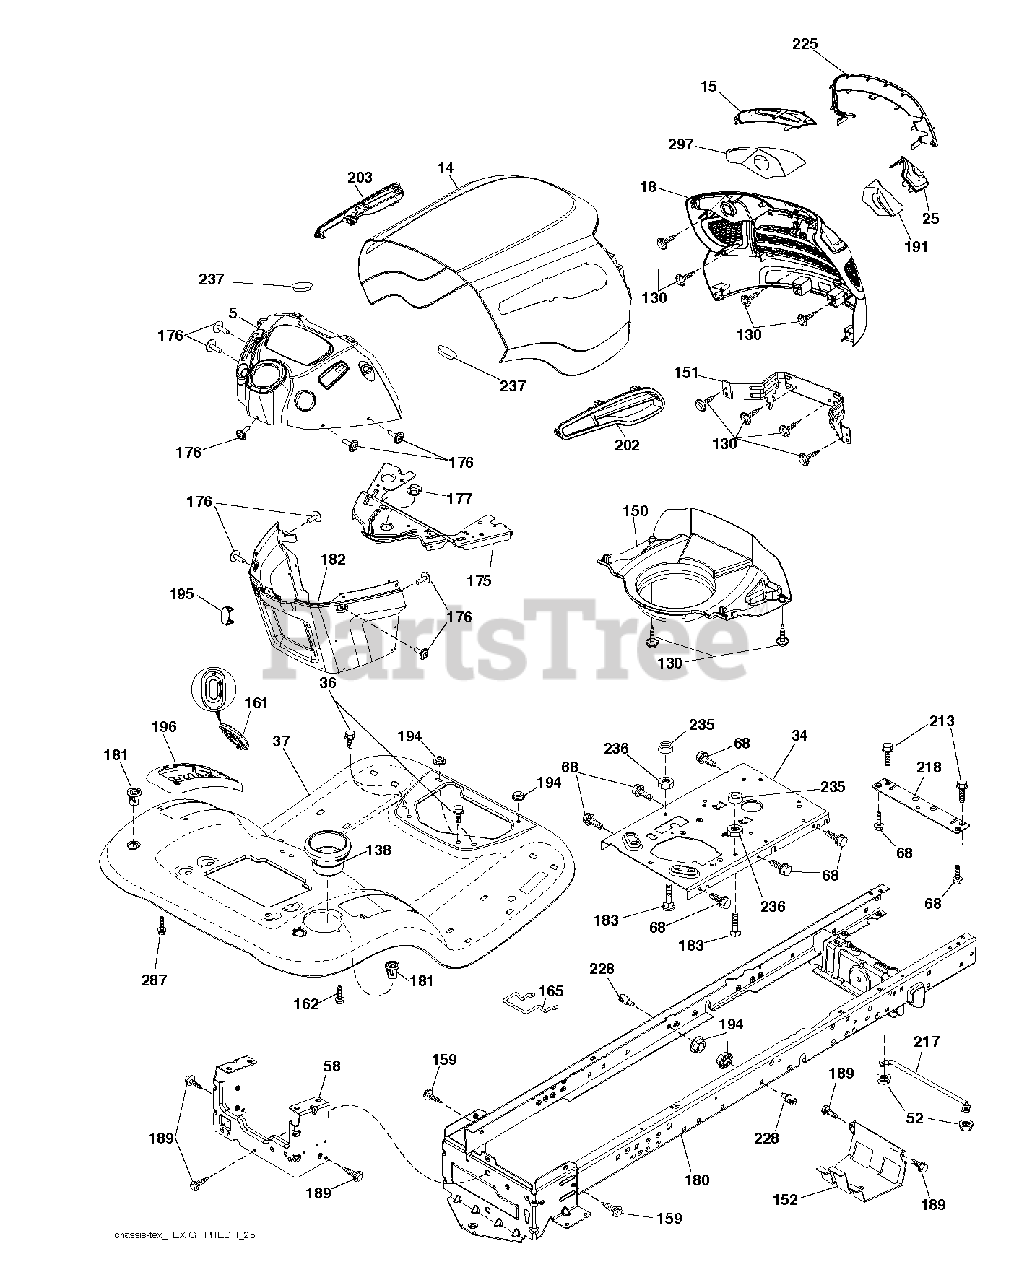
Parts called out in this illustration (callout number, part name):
5	DASH.UPPER.PREDATOR.M/C.BLACK
14	HOOD.PNT.PREDATOR.YT/GT.BLACK
15	LENS.MCCULLOCH.GT.LH
18	GRILLE.PREDGT2.GEN
25	Lens, RH Mcculloch GT
34	PLATE.ENGINE.WELDED.CHASSIS
36	SCREW 5/16"
37	FENDER.TLT.PCH.CPH.FW.ROS.428
52	LOCKNUT
58	DRAWBAR UPPER 2PC SMALL FENDER
68	SCREW LT
130	SCREW.#10 X 0.750.BOS (2 2)
138	CUPHOLDER.TL.TEX.BLACK
150	PREDATOR.YT.GT.HOOD.AIR DUCT
151	BRACKET.PIVOT.PREDATOR
152	SHIELD.BROWNING.W/TEX
159	SCREW, 3/8-16X3/4
161	WINDOW.FUEL.LT.TEX.BLACK
162	SCREW.HI-LO.CONSOLE
165	SUPPORT.TANK.REAR.W/TEX
175	PLATE.CROSSMEMBER.HUSQ
176	SCREW.#10-24X5/8.RN.QU
177	BUSHING STEERING
180	CHASS.WLDMNT.TL.12GA/2P.48/54
181	FEND/FTRST.PCH.CPH.NFW
182	DASH LOWER.HUSQ.PRED NO CRUISE
183	BOLT.5/16-18X1-1/4 FULL THD
189	SCREW
191	REFLECTOR.MCCULLOCH.GT.RH
194	NUT LOCK HEX FLANGE 5/16-18
195	PLUG.HOLE.DASH.
202	VENT.SIDE.HOOD.LH.PREDATOR.BLK
203	VENT.SIDE.HOOD.RH.PREDATOR.BLK
213	BOLT
217	ROD.PIVOT.HOOD
218	X-PIECE.HOOD.STOP.NON/
228	STUD.FASTNER.W/ANTI-ROTATE
235	SPACER FENDER
236	NUT.CENTERLOCK.5/16-
237	PLUG.MOUNT.CARGO.BLK
287	SCREW 1/4X20
297	REFLECTOR.MCCULLOCH.GT.LH
